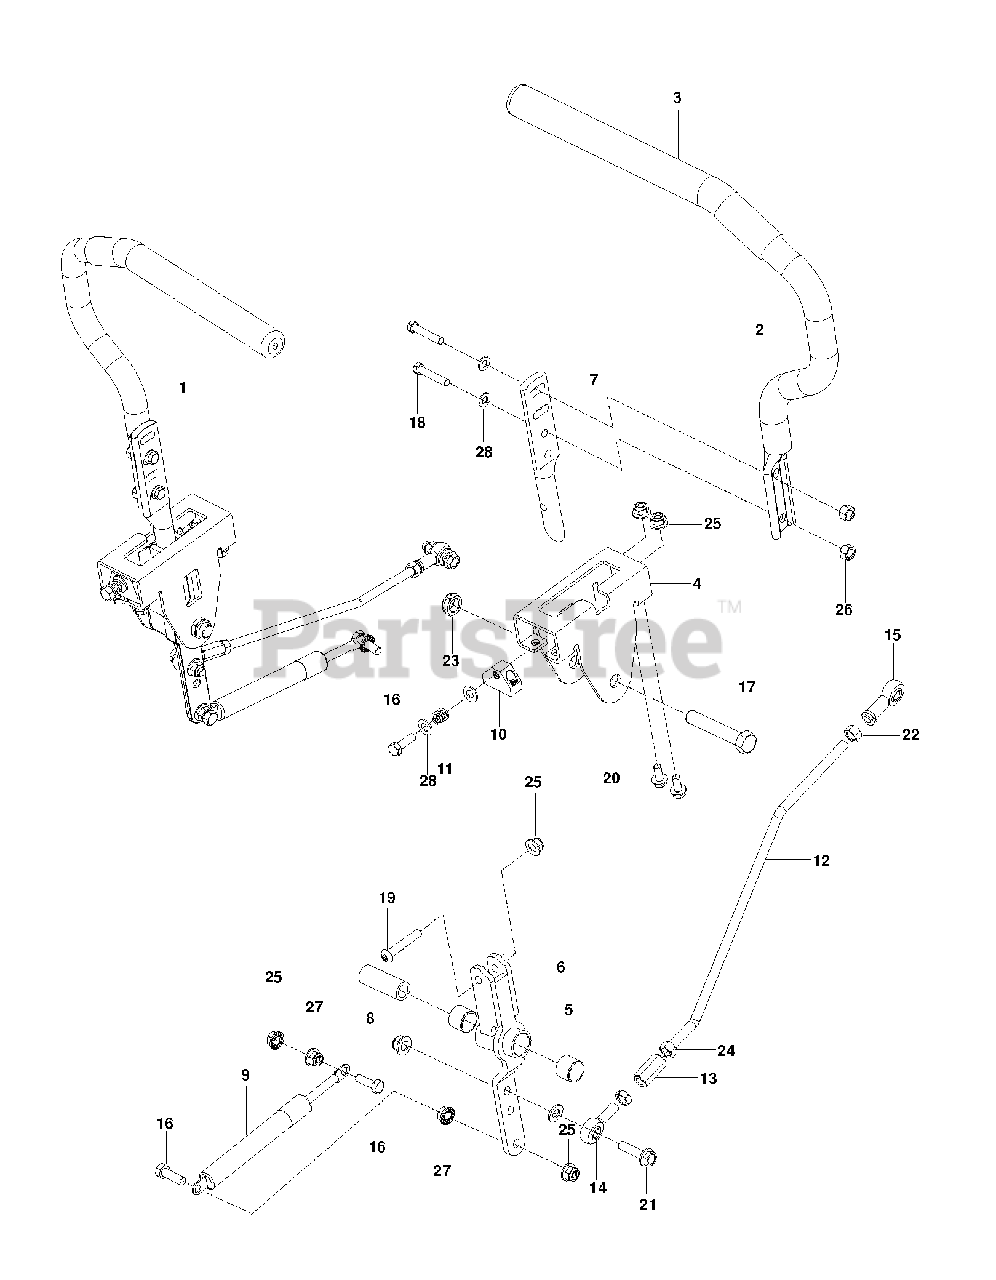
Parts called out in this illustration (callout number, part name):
1	LEVER DRIVE W/GRIP RT
2	LEVER, DRIVE W/GRIP LT
3	GRIP - DRIVE LEVER
4	BRACKET, CONTROL
6	Control Weldment.Rz
7	LEVER.HANDLE MOUNT
8	Pivot Control Spacer
10	BLOCK, TRACKING
12	ROD, CONTROL
13	ROD END COUPLER
14	RH ROD END
15	ROD END LH
16	BOLT.5/16-18X1-1/4 FULL.THREAD
17	Hex Capscrew, 1/2-13 X 2-3/4 Gd 5 Zd
18	CAPSCREW 5/16 X 1/1/2 HEX HEAD
19	Buttonhead Screw, 5/16-18 X 1-3/4
20	HHFS 5/16-18 X 3/4
21	HHFS 5/16-18 X 1.25 TPBLT GD 5
22	NUT 5/16F
23	NUT 1/2-13 HEX JM NYL
24	NUT 5/16F LEFTHAND
25	5/16-18 NYLOC FLANGE NUT
26	NUT 5/16 NYLOC
27	NUT 5/16C WHIZ
28	WASHER
